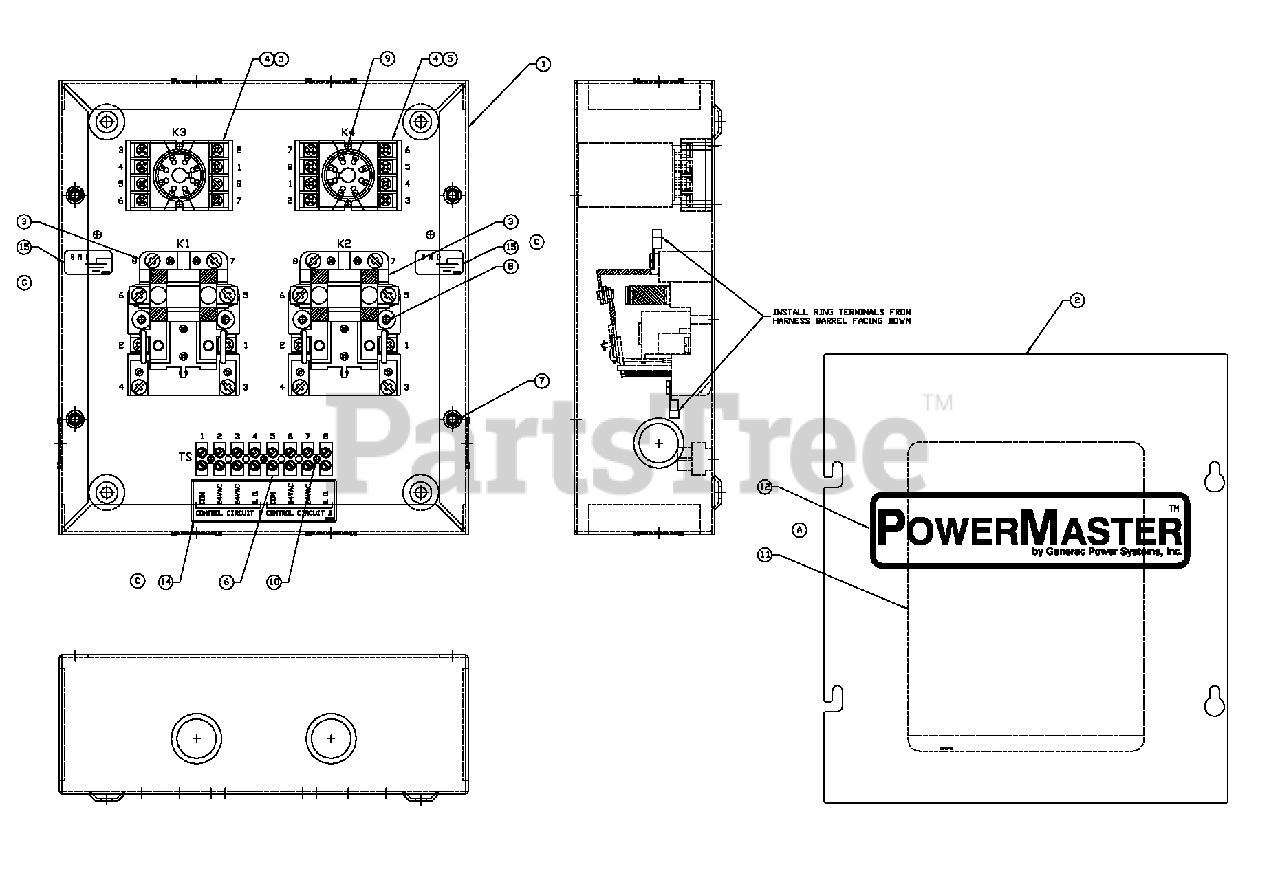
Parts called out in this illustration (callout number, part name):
1	LOAD DISCONNECT ENCLOSURE
2	LOAD DISCONNECT ENCLOSURE COVER
3	RELAY 40A @ 300VAC DPDT
4	RELAY DPDT 24VAC 5A 8 PIN
5	SOCKET RELAY 8 PIN
6	BLOCK TERM 10MM 8 POS MOLEX
7	SCREW HHTT M5-0.8 X 10 BP
8	SCREW PHTT M4-0.7 X 12 ZYC
9	SCREW PHTT M4-0.7 X 20 ZYC
10	SCREW PHTT #6-32 X 5/8 ZYC
11	DECAL, FIELD WIRING
12	DECAL, FRONT COVER
14	DECAL, POWERMASTER CONTROL
15	DECAL, GROUND LUG
